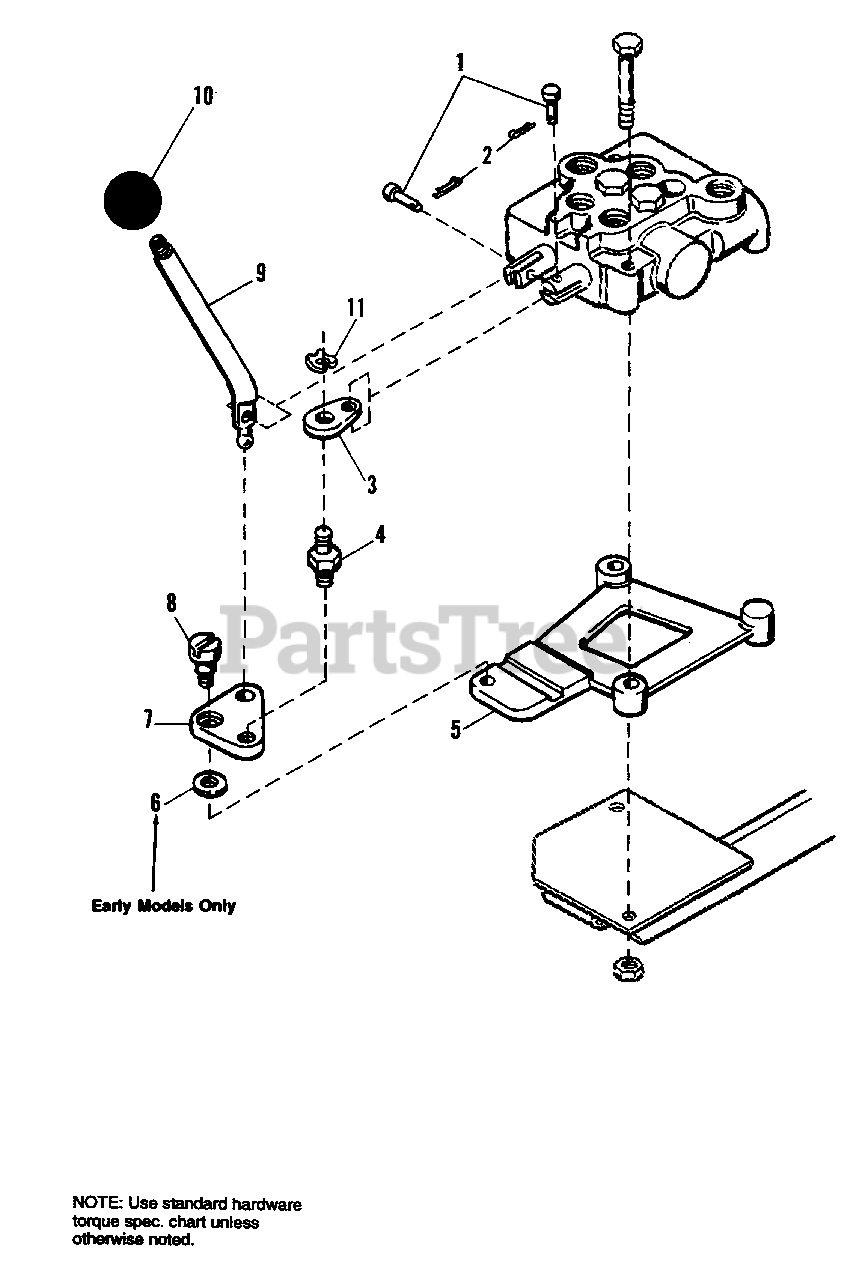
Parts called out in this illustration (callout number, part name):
1	PIN, Spool, 1/4 x 3/4
2	PIN, Cotter, 1/16 x 1/2
3	LINK, Spool
4	STUD, Pivot Plate
5	PLATE, Lever Mounting
6	WASHER, Curved Spring
7	PLATE, Lever Pivot
8	SCREW, Shoulder
9	LEVER, Valve
10	KNOB, Lever Replacement
11	CLIP, Retainer
